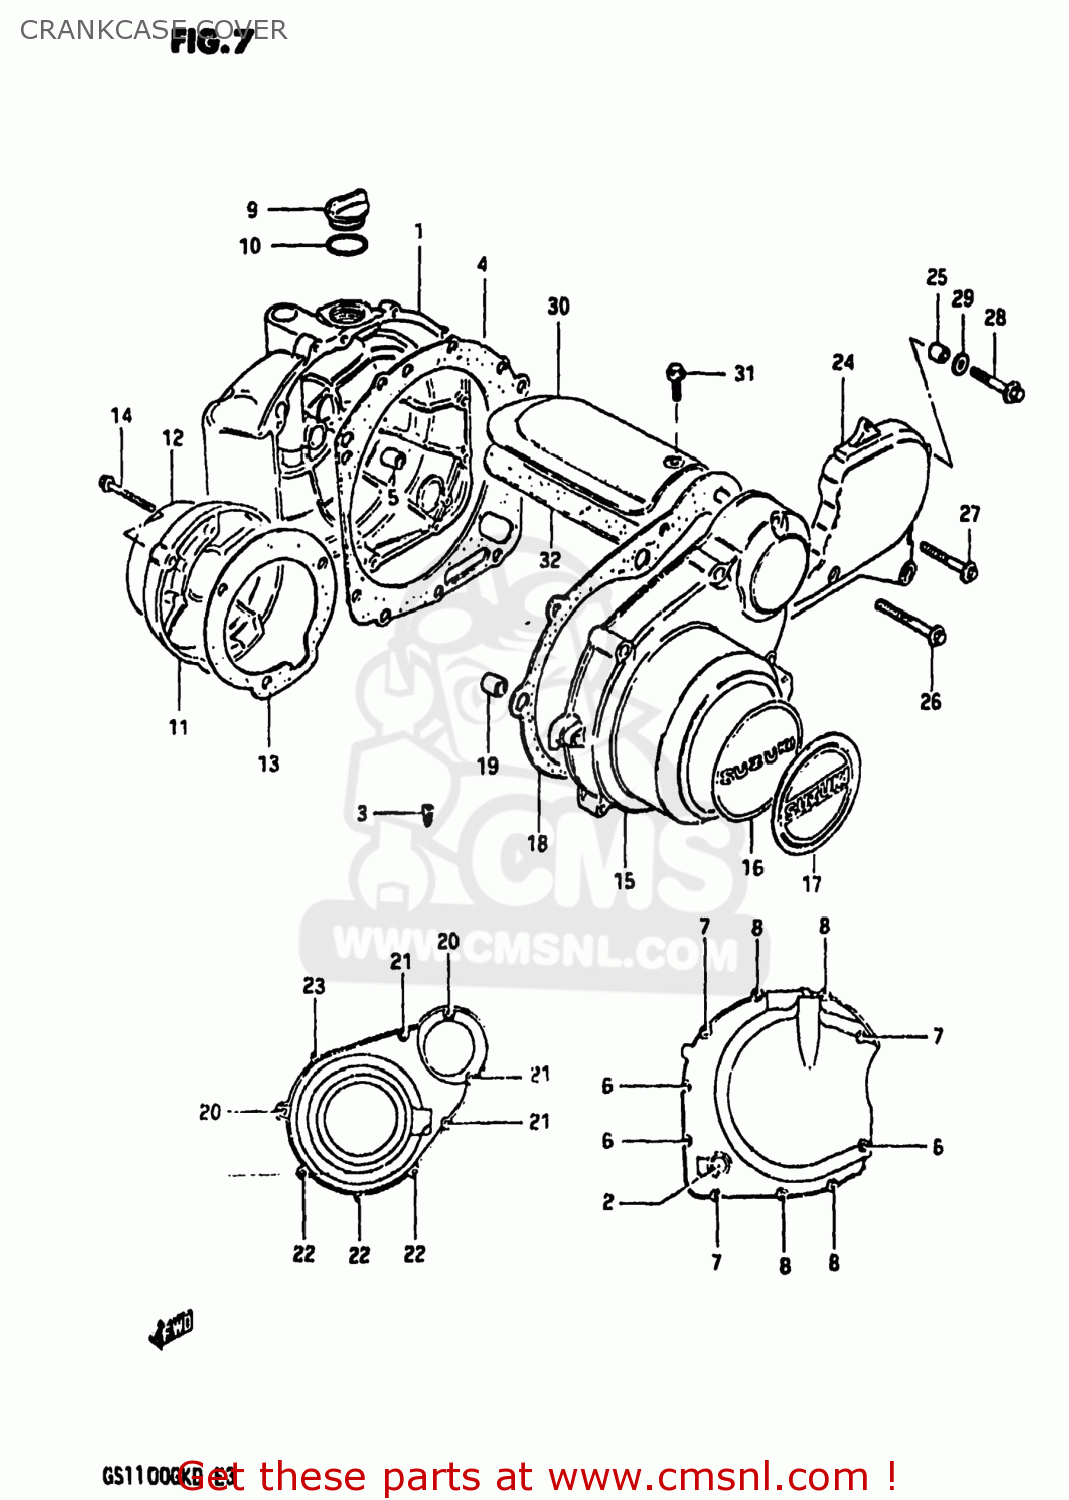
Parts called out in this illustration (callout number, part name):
1	COVER,CLUTCH
2	LENS,OIL LEVEL CHECK
3	JET
4	GASKET,MAGNETO COVER (N (MCA)
5	PIN
6	BOLT (6X35)
7	BOLT (6X30)
8	BOLT
9	CAP
10	O RING(D:2.2,ID:32)
11	COVER,CONTACT BREAKER
12	EMBLEM,CONTACT BREAKER COVER
13	GASKET,CONTACT BREAKER COVER (NAS)
14	BOLT (5X30)
15	COVER,MAGNETO
16	EMBLEM,MAGNETO COVER
17	EMBLEM,MAGNETO COVER
18	GASKET,MAGNETO COVER (MCA)
19	PIN
20	BOLT
21	BOLT (6X40)
22	BOLT (6X35)
23	BOLT (6X30)
24	COVER,SECONDARY DRIVE
25	PIN
26	BOLT (6X30)
27	BOLT
28	BOLT (6X20)
29	WASHER
30	COVER,STARTER MOTOR
31	BOLT
32	GASKET,STARTER MOTOR COVER (MCA)
